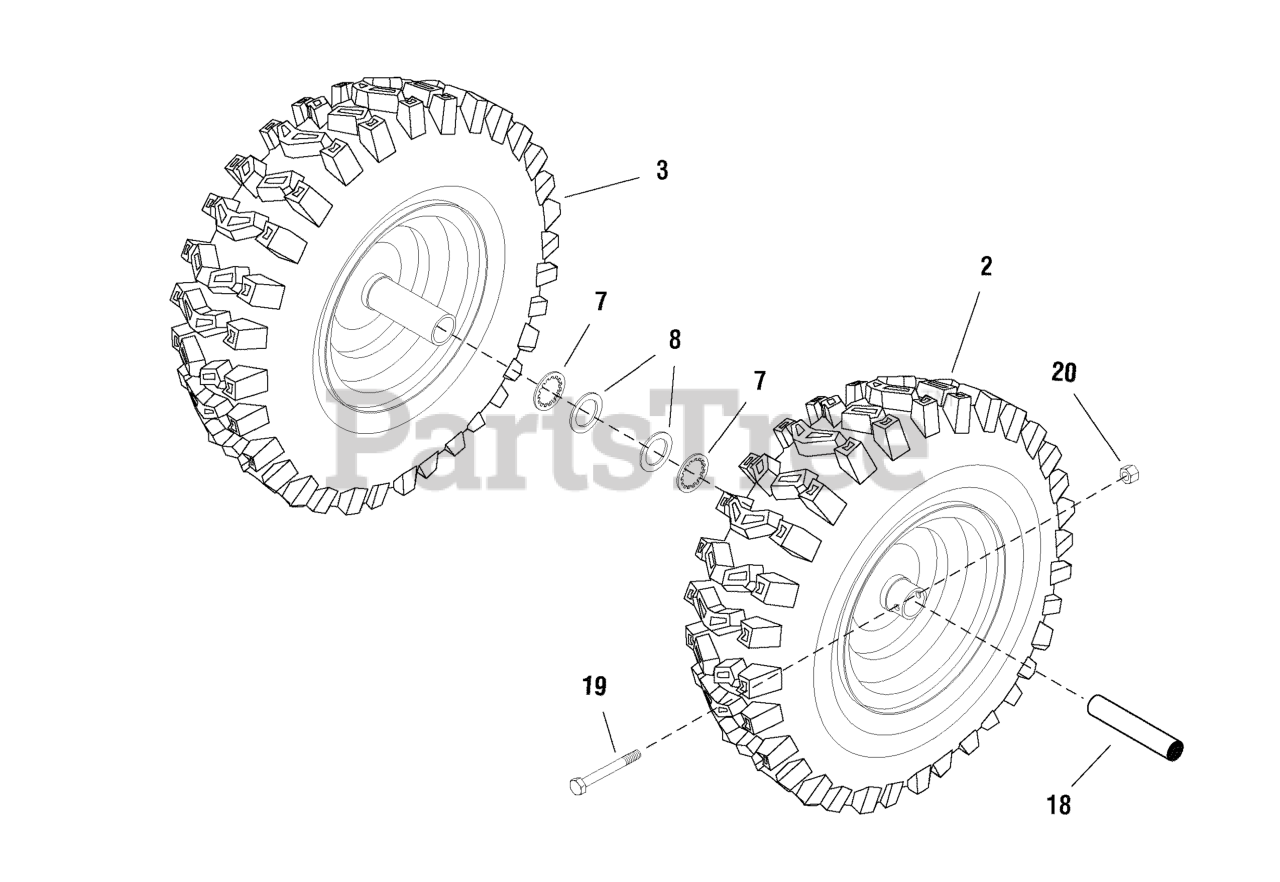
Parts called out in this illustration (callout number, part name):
2	WHEEL & TIRE ASSEMBLY, L.H. SNOW XTRAC 16 x 4.8-8
3	WHEEL & TIRE ASSEMBLY, R.H. SNOW XTRAC 16 x 4.8-8
7	RETAINER, Ring
8	WASHER, Flat .765 x 1.12 x .06 YZ
18	BUSHING, WHEEL
19	SCREW, 1/4-20 X 1.75 HH
20	NUT, 1/4-20 HEX NYLOCK
